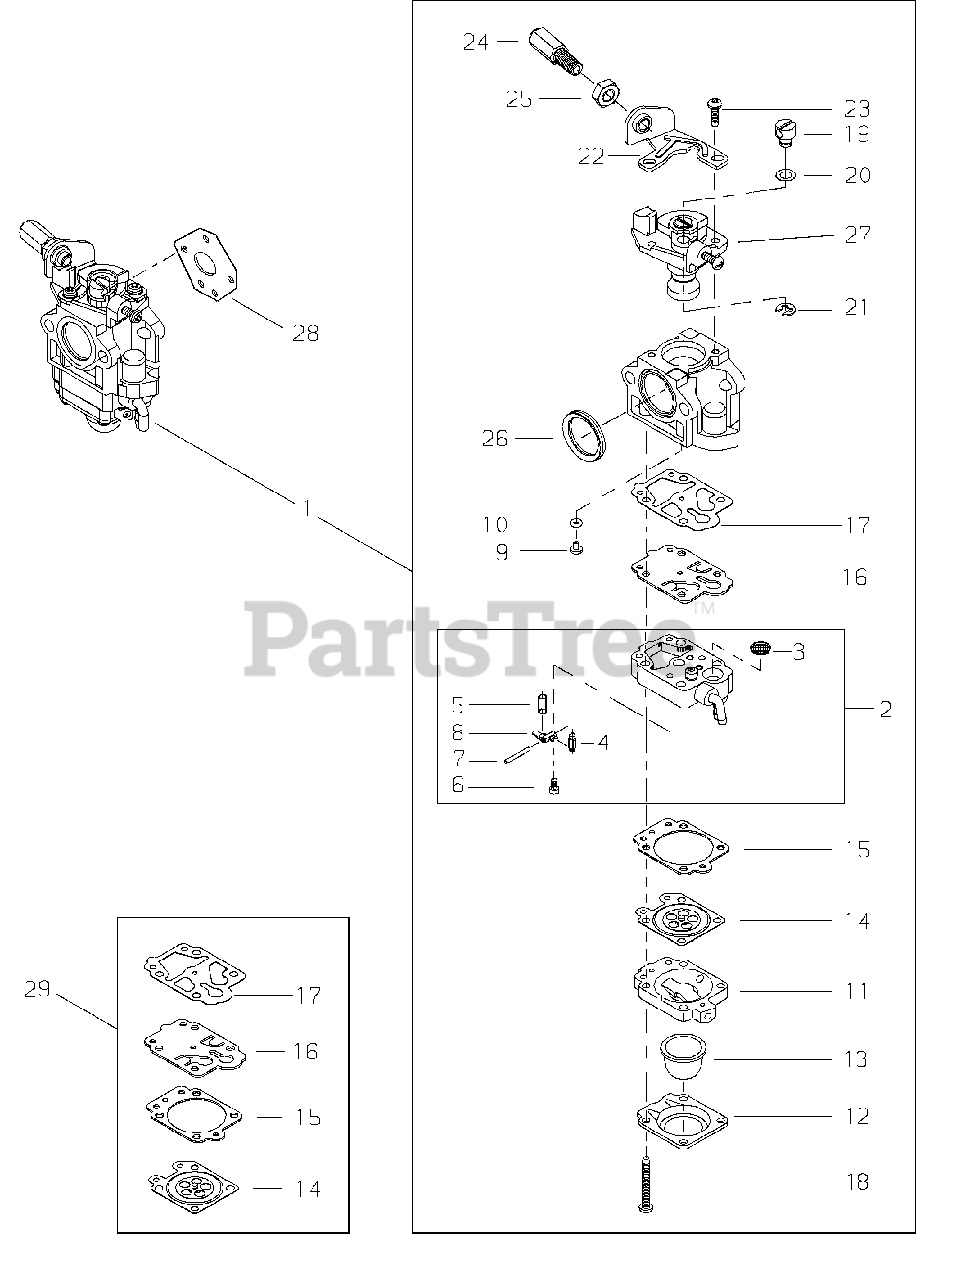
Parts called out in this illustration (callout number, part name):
1	CARBURETOR
2	BODY ASSY, PUMP
3	SCREEN, FUEL INLET
4	VALVE, INLET NEEDLE
5	SPRING, METERING LEVER
6	SCREW, METERING LEVER PIN
7	PIN, METERING LEVER
8	LEVER, METERING
9	JET, MAIN
11	BODY ASSY, PURGE
12	RETAINER, PURGE BULB
13	BULB, PURGE
14	DIAPHRAGM, METERING
15	GASKET, METERING DIAPHRAGM
16	DIAPHRAGM, PUMP
17	GASKET, PUMP
21	RING, SNAP
22	BRACKET, THROTTLE CABLE
23	SCREW, THROTTLE COLLAR
24	ADJUSTER, THROTTLE CABLE
26	RING, PACKING
27	VALVE ASSY, THROTTLE
28	GASKET, INTAKE
29	GASKET KIT
